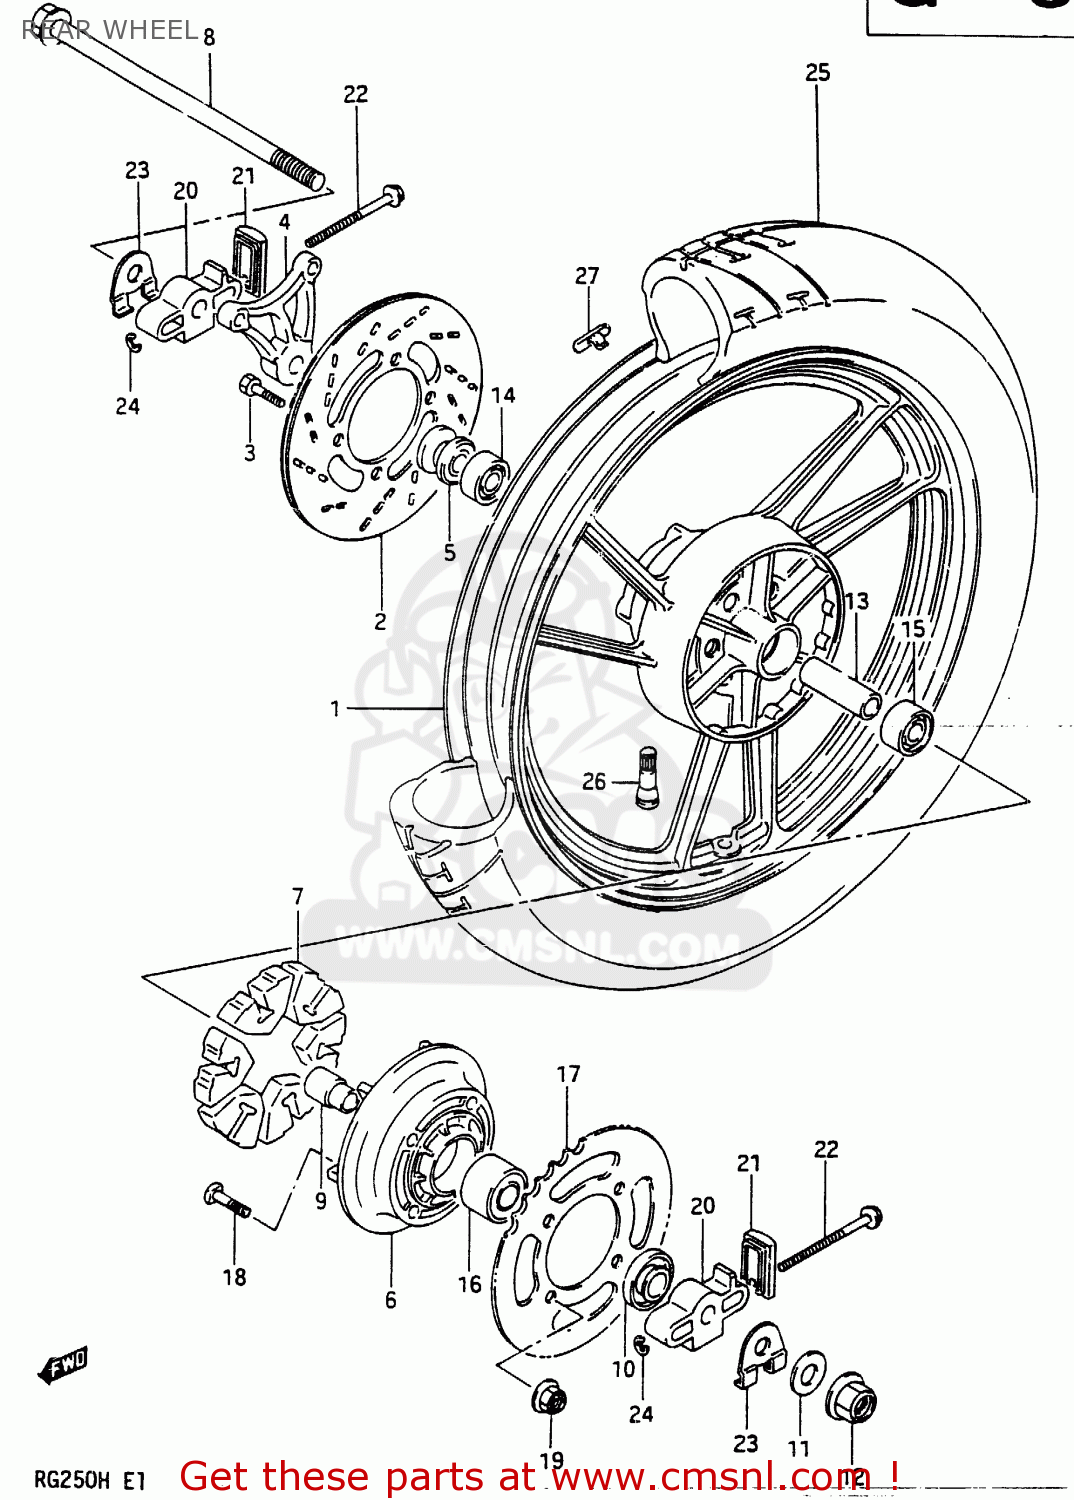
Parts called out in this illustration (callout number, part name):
1	WHEEL, REAR (MT2.15X18) WHITE
2	DISC,REAR BRAKE (BLACK)
3	BOLT
4	BRACKET, CALIPER
5	SPACER, RH
6	DRUM,REAR SPROCKET MOUNT
7	ABSORBER,RR HUB SHOCK
8	AXLE, REAR
9	RETAINER,RR SPROCKET MTG
10	SPACER, LH
11	WASHER(14.2X26X1.2)
12	NUT
13	SPACER
14	BEARING
15	BEARING
16	BEARING
17	SPROCKET,RR(NT:39)
18	BOLT(8X36)
19	NUT
20	BODY, CHAIN ADJUSTER
21	PLATE, GUIDE
22	BOLT,CHAIN ADJUSTER
23	WASHER,CHAIN ADJUSTER
24	E RING
25	TIRE, T/L REAR (110/80H18)
26	VALVE,TIRE
27	BALANCER,WHEEL(10G)
